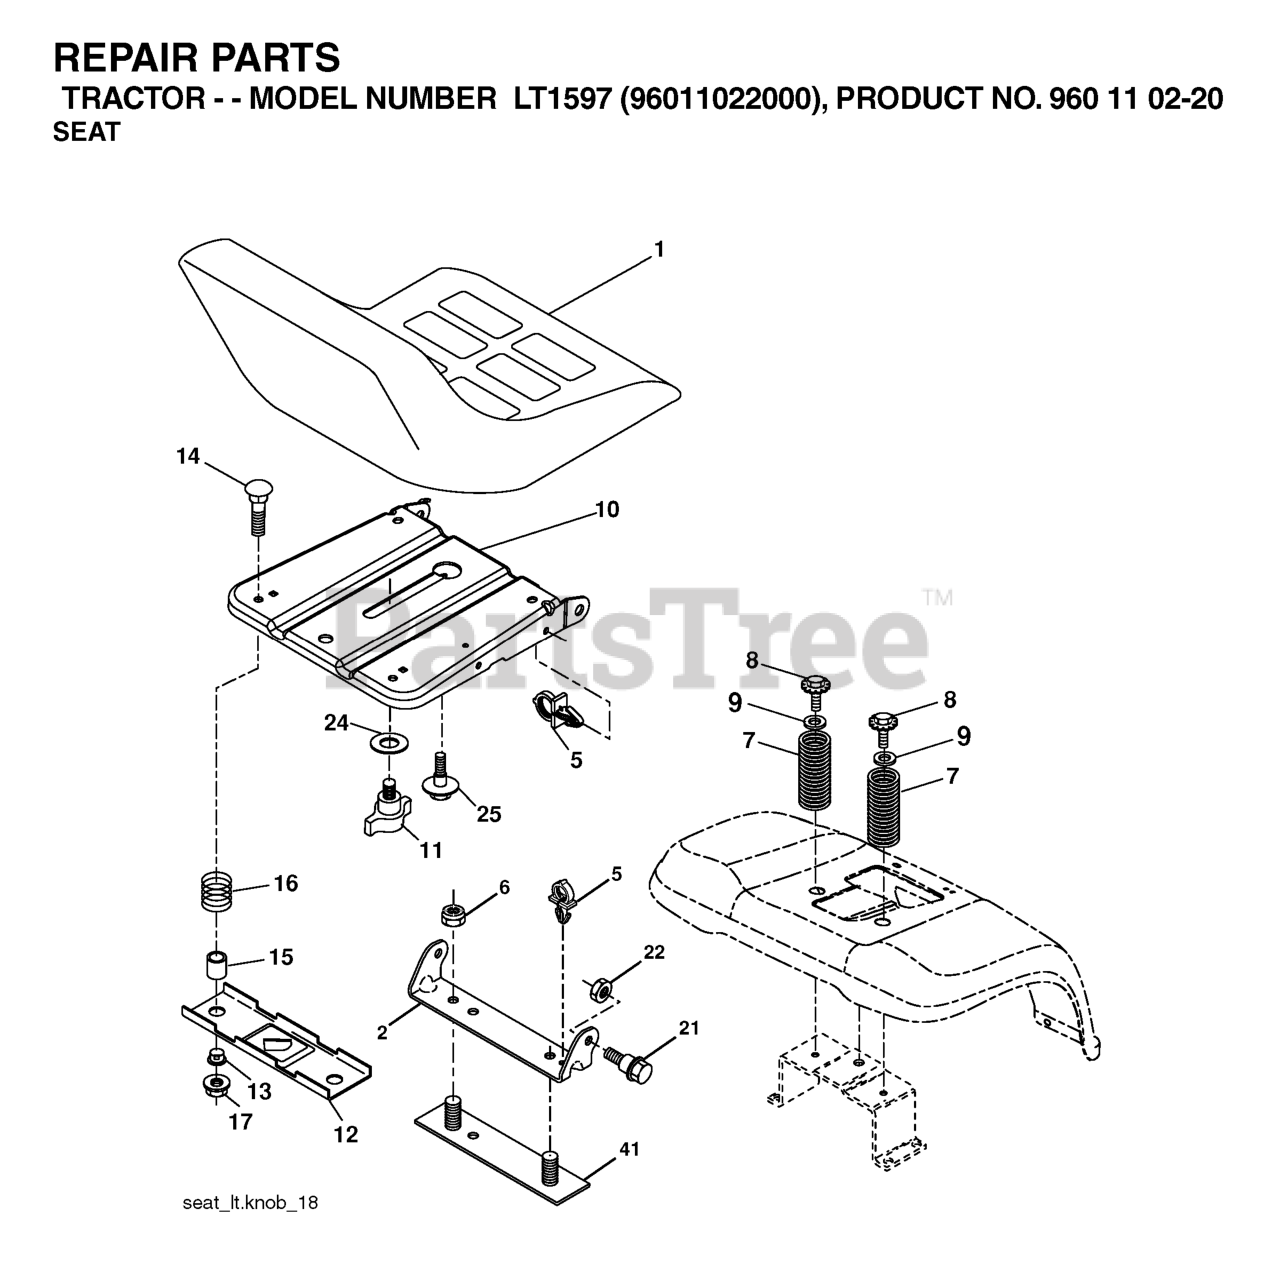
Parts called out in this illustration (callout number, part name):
1	RP SEAT
2	SEAT PIVOT BRKT
6	NUT
7	SPRING COMPRESSION
8	SCREW 3/8-16X1
9	WASHER
10	PAN.ASM.SEAT.1SLOT
11	KNOB.SEAT.ADJ.WINGNUT
12	BRKT.MNTNG.SWITCH.SEAT.BLACK
14	BOLT.ROUND.HEAD.SQUARE.NECK
15	SPACER SPLIT 28X.96
17	NUT T
21	BOLT.SHOULDER.5/16-18
22	NUT.71038.31-18.HEX.NYLOCK
25	BOLT,SHOULD
41	STRAP
